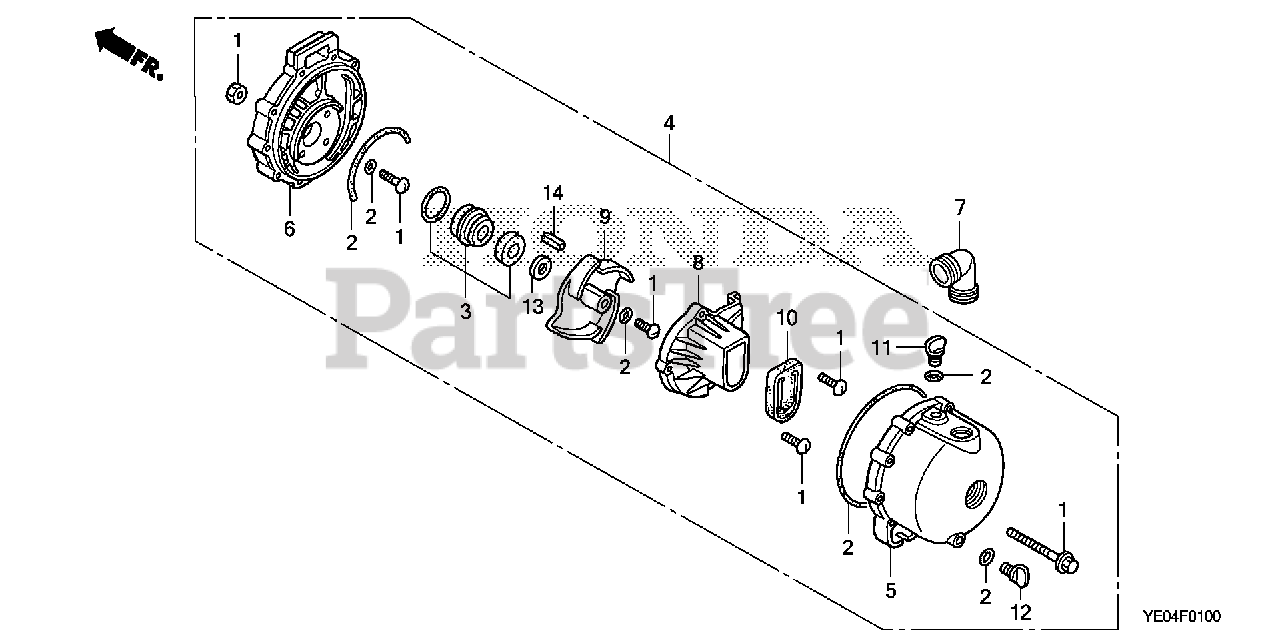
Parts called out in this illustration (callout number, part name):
1	HARDWARE SET
2	O-RING SET
3	SEAL SET, MECHANICAL
4	PUMP ASSY. (SE2RL)
5	PUMP ASSY. (SE2RL)
6	PUMP ASSY. (SE2RL)
8	PUMP ASSY. (SE2RL)
10	VALVE, CHECK
11	CAP, FILLER
12	PLUG, DRAIN
13	SHIM A, IMPELLER (0.006")
13	SHIM B, IMPELLER (0.015")
13	SHIM C, IMPELLER (0.030")
